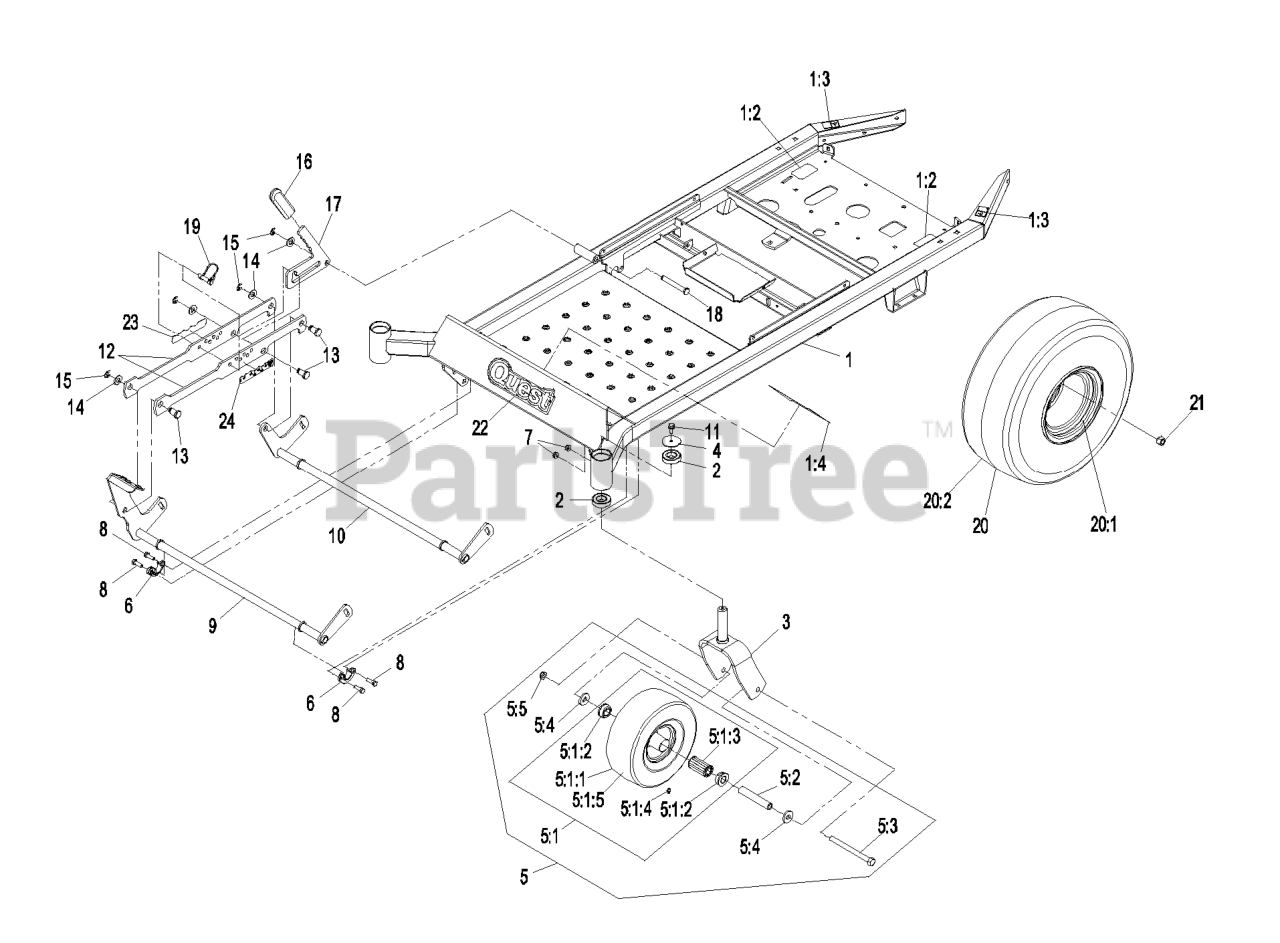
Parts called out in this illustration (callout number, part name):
1:2	DECAL-DRIVE RELEASE
1:3	DECAL-WARNING
1:4	DECAL-SAFETY
2	BEARING-BALL
3	WLD,CASTER FORK
5	ASM,SAWTOOTH WHEEL
5:1	FRONT WHEEL AND TIRE ASM
5:1:1	TIRE
5:1:2	BUSHING-FLANGE
5:1:3	BEARING
5:1:4	FITTING-GREASE
5:1:5	TUBE-INNER (W/VALVE)
5:2	BUSHING-SPANNER
5:3	SCREW-HH
5:4	WASHER-FLAT
5:5	NUT-HEX
6	BEARING-FLANGE
7	NUT-HF, NI
8	SCREW-HH
9	WLD,FRONT SHAFT
10	WLD,REAR SHAFT
11	SCREW-HHF
12	LINK
14	WASHER-FLAT
15	RING-RETAINING, EXTERNAL
16	GRIP-LEVER
18	PIN-CLEVIS
19	PIN-LYNCH
20	WHEEL AND TIRE ASM
20:1	WHEEL
20:2	TIRE
21	NUT-LUG
22	DECAL,QUEST LOGO
23	DECAL,HEIGHT OF CUT
24	DECAL,HEIGHT OF CUT
